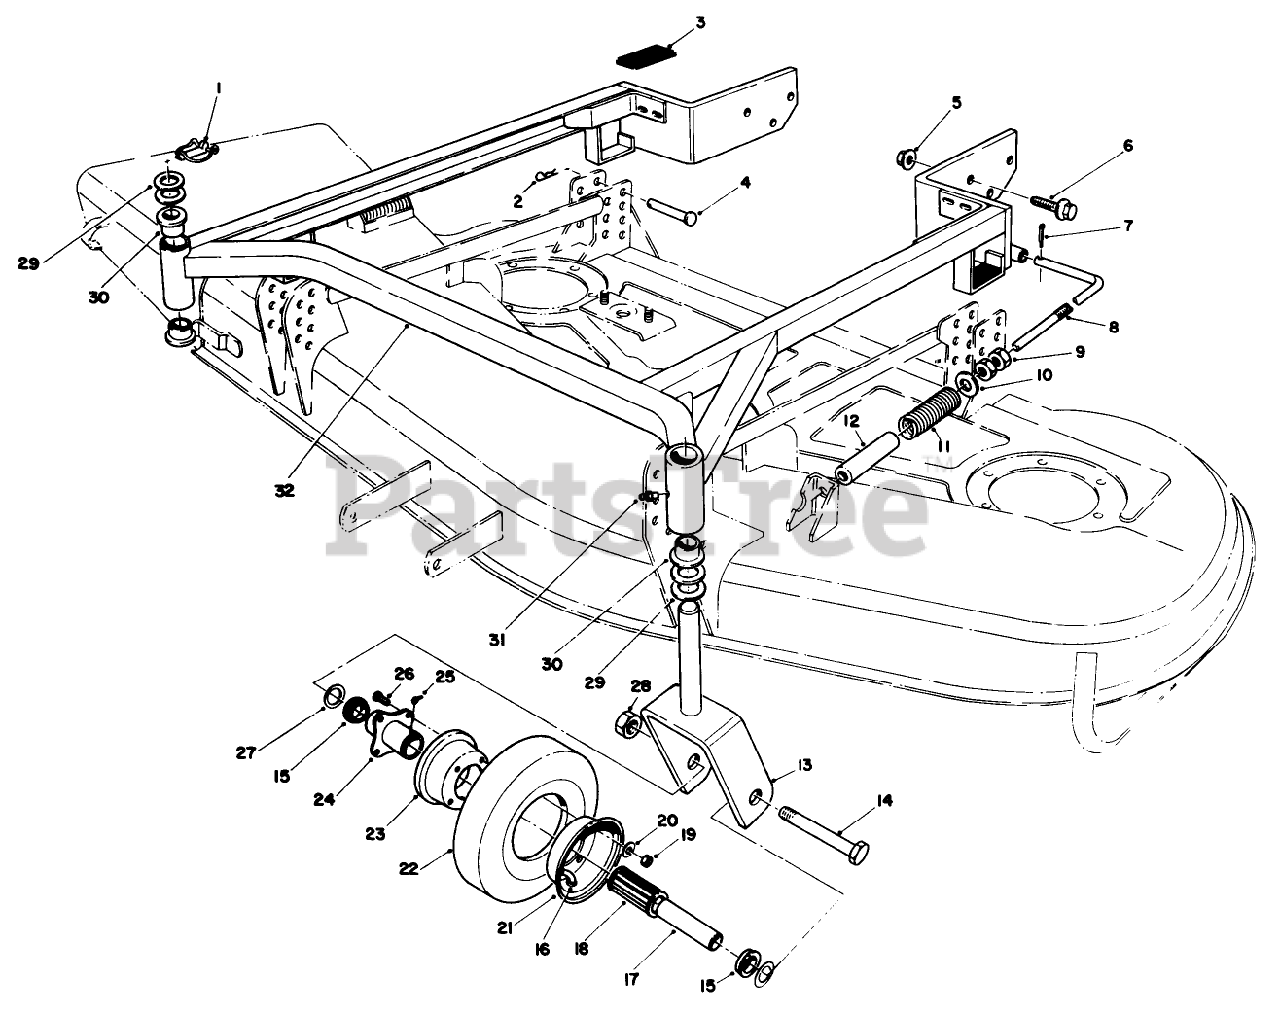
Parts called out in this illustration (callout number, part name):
1	PIN-LYNCH
2	PIN-HAIR
4	PIN-CLEVIS
5	NUT-HF
6	SCREW-HHF
7	PIN-COTTER
9	NUT-JAM
10	WASHER
14	SCREW-HH
15	RETAINER
18	ROLLER BEARING
19	NUT-HEX
20	WASHER-LOCK
21	WHEEL HALF-FEMALE
22	TIRE 8"(4-PLY)
23	WHEEL HALF-MALE
24	HUB - CENTERED
25	FITTING-GREASE
26	WHEEL BOLT
27	WHEEL SPACER
28	NUT-LOCK
29	WASHER-THRUST
31	FITTING-GREASE
